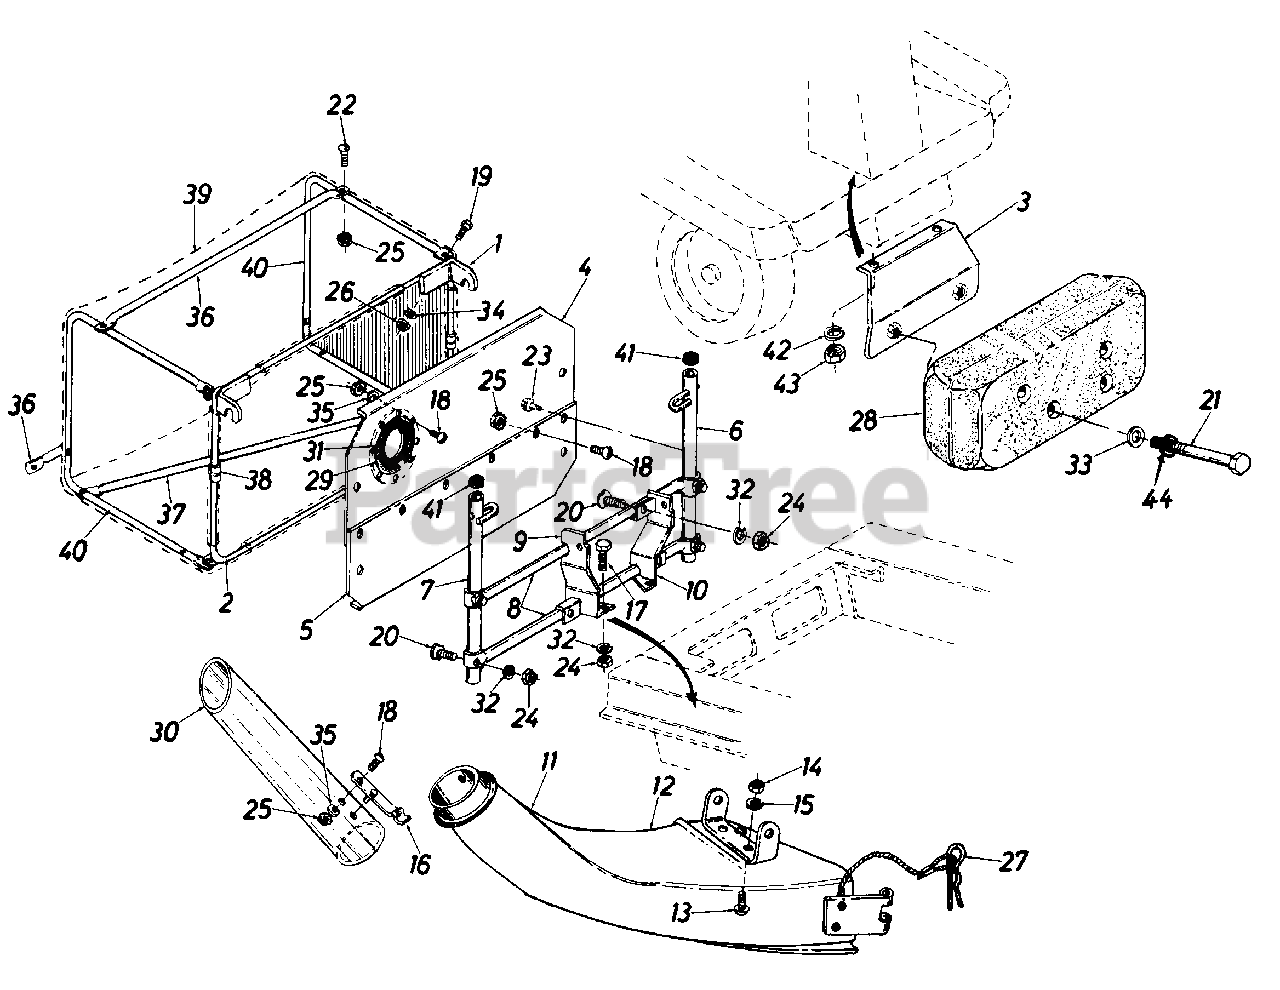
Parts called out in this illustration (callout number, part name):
1	Catcher Frame Ass'y.-Upper
2	Catcher FrameAss'y.-Lower
3	Counterweight Support Bracket. Ass'y.
4	Front Cover-Upper Half
5	Front Cover-Lower Half
6	L.H. Vertical Support Ass'y.
7	R.H. Vertical Support Ass'y.
8	Horizontal Support Tubing
9	Catcher Support Brkt. Ass'y.-R.H.
10	Catcher Support Brkt. Ass'y.-L.H.
11	Discharge Chute Ass'y.
12	Brkt. Chute Hinge
13	Carr. Bolt 1/4-20 x .62" Lg.
14	Hex Nut 1/4-20 Thd.
15	L-Wash. 1/4" I.D.
16	Spring Lock Ass'y.
17	Hex Bolt 5/16-18 x .75" Lg.
18	Truss Mach. Scr. #10-24 x .38" Lg.
19	Hex Bolt 1/4-20 x .62" Lg.
20	Curved Carr. Bolt 5/16-18 x 1.75" Lg.
21	Hex Bolt 3/8-16 x 4.50" Lg.
22	Truss Mach. Scr. #10-24 x 1.0" Lg.
23	Hex Wash. Hd. AB-Tap Scr. 1/4" x.62" Lg.
24	Hex Nut 5/16-18 Thd.
25	Hex Sems Nut #10-24 Thd.
26	Hex Nut 1/4-20 Thd.
27	Internal Cotter Pin
28	Counter Weight-38#
29	Trim Strip-24"
30	Grass Chute Tube
31	Rubber Flap
32	L-Wash. 5/16 " I.D.
33	Flat Washer 3/8" I.D. x 1.25" O.D. x .17
34	L-Wash. 1/4" I.D.
35	Fl-Wash. .203" I.D. x .41" O.D. x .040
36	Grass Catcher Handle
37	Grass Catcher Handle
38	Tubing Connector 1/2" I.D.
39	Grass Bag
40	CatcherSide Frame
42	L-Wash.5/16" I.D.
43	Hex Nut 5/16-18 Thd.
44	Bell-Wash. 3/8" I.D. x 7/8" O.D.
